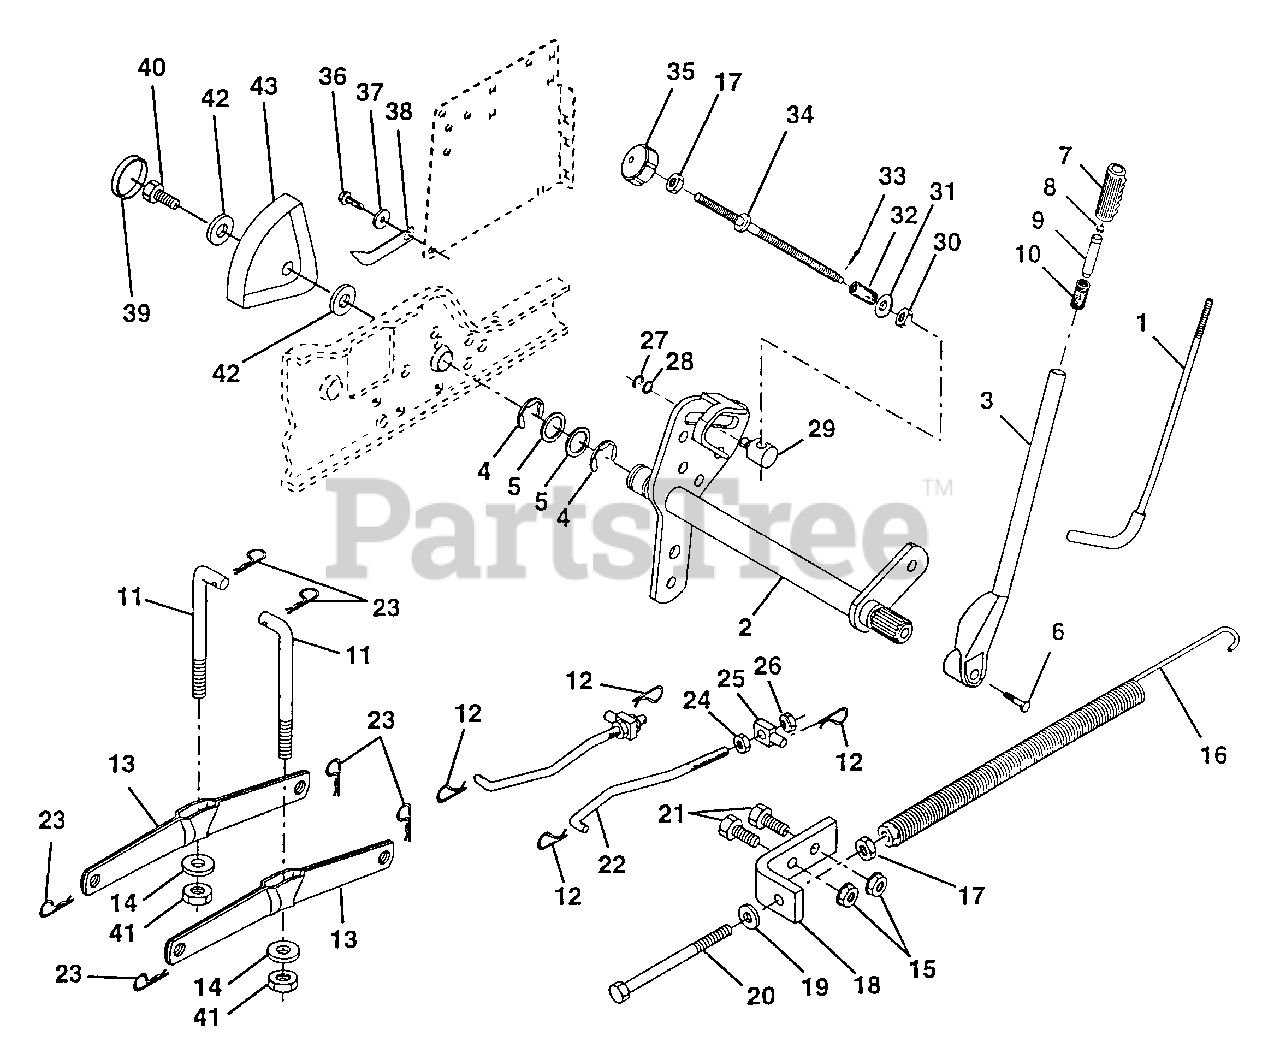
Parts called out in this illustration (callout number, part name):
1	Rod Asm., Lever
2	Shaft Asm., Lift Vgt (AYP part number)
3	Lever Asm., Lift Rh (AYP part number)
4	E-Ring Truarc #5133-87
5	Washer 29/32 x 1-1/4 x 16 Ga.
6	Bolt, Fin Hex 3/8-16 x 1-1/2
7	Grip, Handle Bicycle
8	Button, Plunger (AYP part number)
9	Plunger, Lever Lift (AYP part number)
10	Spring 2-1/8"
11	Link Lift (AYP part number)
12	Retainer, Spring
13	Arm, Suspension Vgt
14	Bearing (AYP part number)
15	Nut, Crownlock 3/8-16
16	Spring Asm., Assist Lift
17	Nut, Hex Jam 3/8-16 Unc
18	Bracket, Spring Assist
19	Washer 13/32 x 13/16 x 16 Ga.
20	Bolt, Adjust Spring Assist
21	Bolt, Fin Hex 3/8-16 x 1
22	Link, Front (AYP part number)
23	Retainer, Spring (AYP part number)
24	Nut, Jam Hex 1/2-13 Unc
25	Trunnion (AYP part number)
26	Nut, Lock ash 1/2-13 Unc (AYP part number)
29	Trunnion Infin Height
30	Nut, Special
31	Washer 13/32 x 5/8 x 16 Ga.
32	Spring, Compression Inf Hgt
33	Pin, Cotter 3/32 x 1/2 (AYP part number)
34	Rod, Adj Lift
35	Knob, Inf 3/8-16 Unc
38	Pointer Height Indicator
39	Plug, Hole Blk. 1.485/1.515 Dia.
40	Screw Thdrol 5/16-18 x 3/4
41	Nut, Crownlock 3/8-24 (AYP part number)
42	Washer 11/32 x 1-1/2 x 10 Ga.
43	Scale, Indicator Height
70	Nut Hex Flange Lock
72	Nut Push Phos & Oil (AYP part number)
